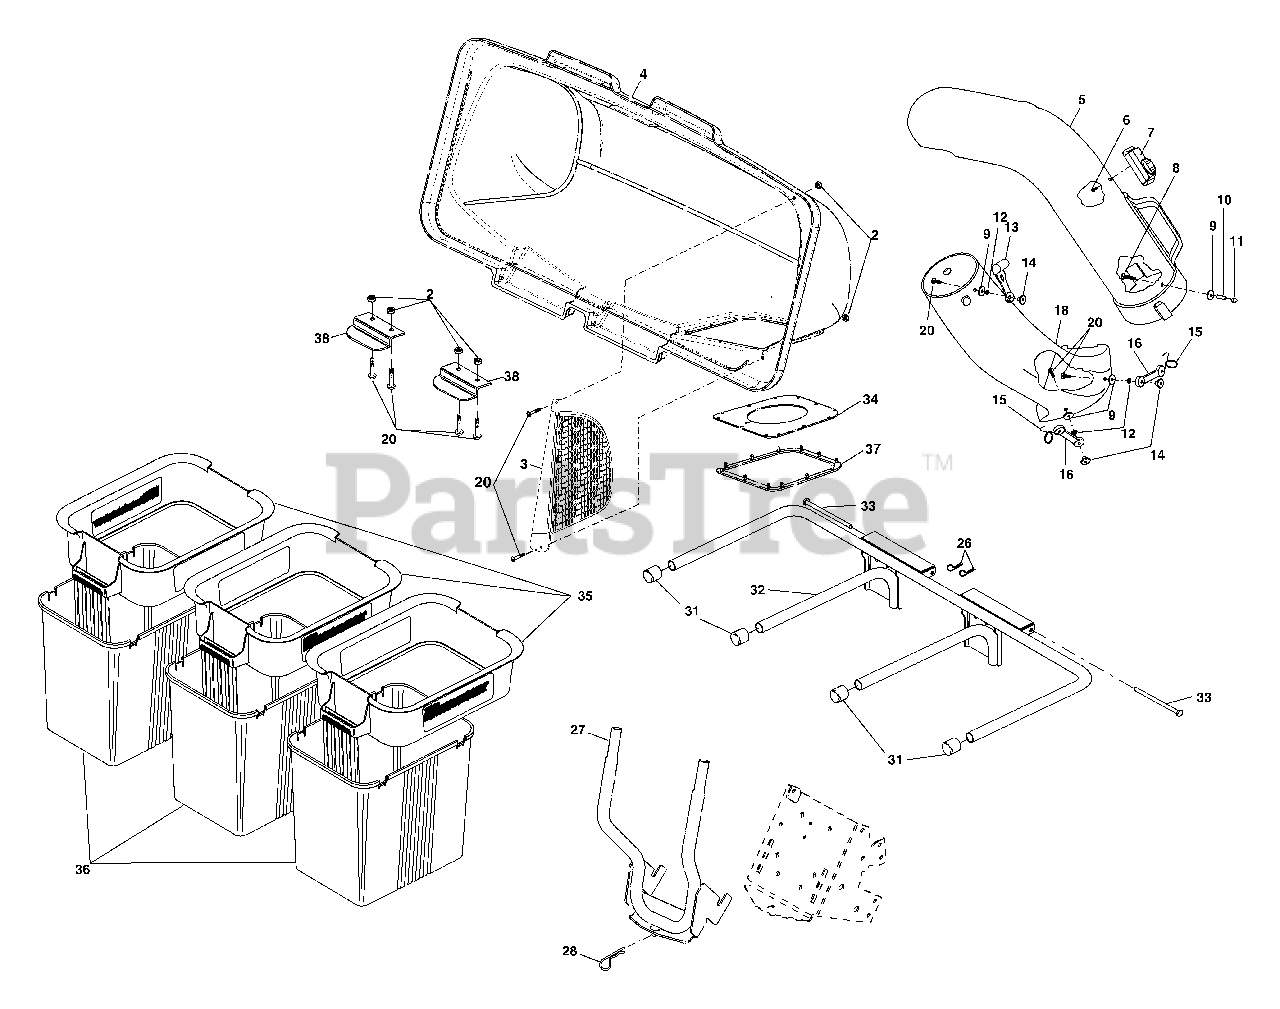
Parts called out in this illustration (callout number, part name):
2	Nut, Crownlock #10-24
3	Screen, Cover
4	Cover Assembly
5	Chute, Upper
6	Screw, Special #10-14x1/2
7	Full bag Indicator
8	Screw, #10-24 x 1-1/8
9	Washer 3/16x3/4x16 Ga.
10	Spacer, Split
11	Nut, Acorn #10-24
12	Washer, lock
13	Latch, Chute
14	Nut, Weld
15	Latch, Hook
16	Rubber, Latch
18	Chute, Lower
20	Screw #10-24 x 5/8
26	Spring, Retainer
27	Support Assembly "A"
27	Support Assembly "B"
28	Spring, Retainer
31	Plug, Tubing End
32	Bagger, Frame
33	Pin, Hinge
34	Gasket, Cover
35	Container, Top
36	Container, Bottom
37	Ring, Cover Gasket
38	Latch Handle, Cover
